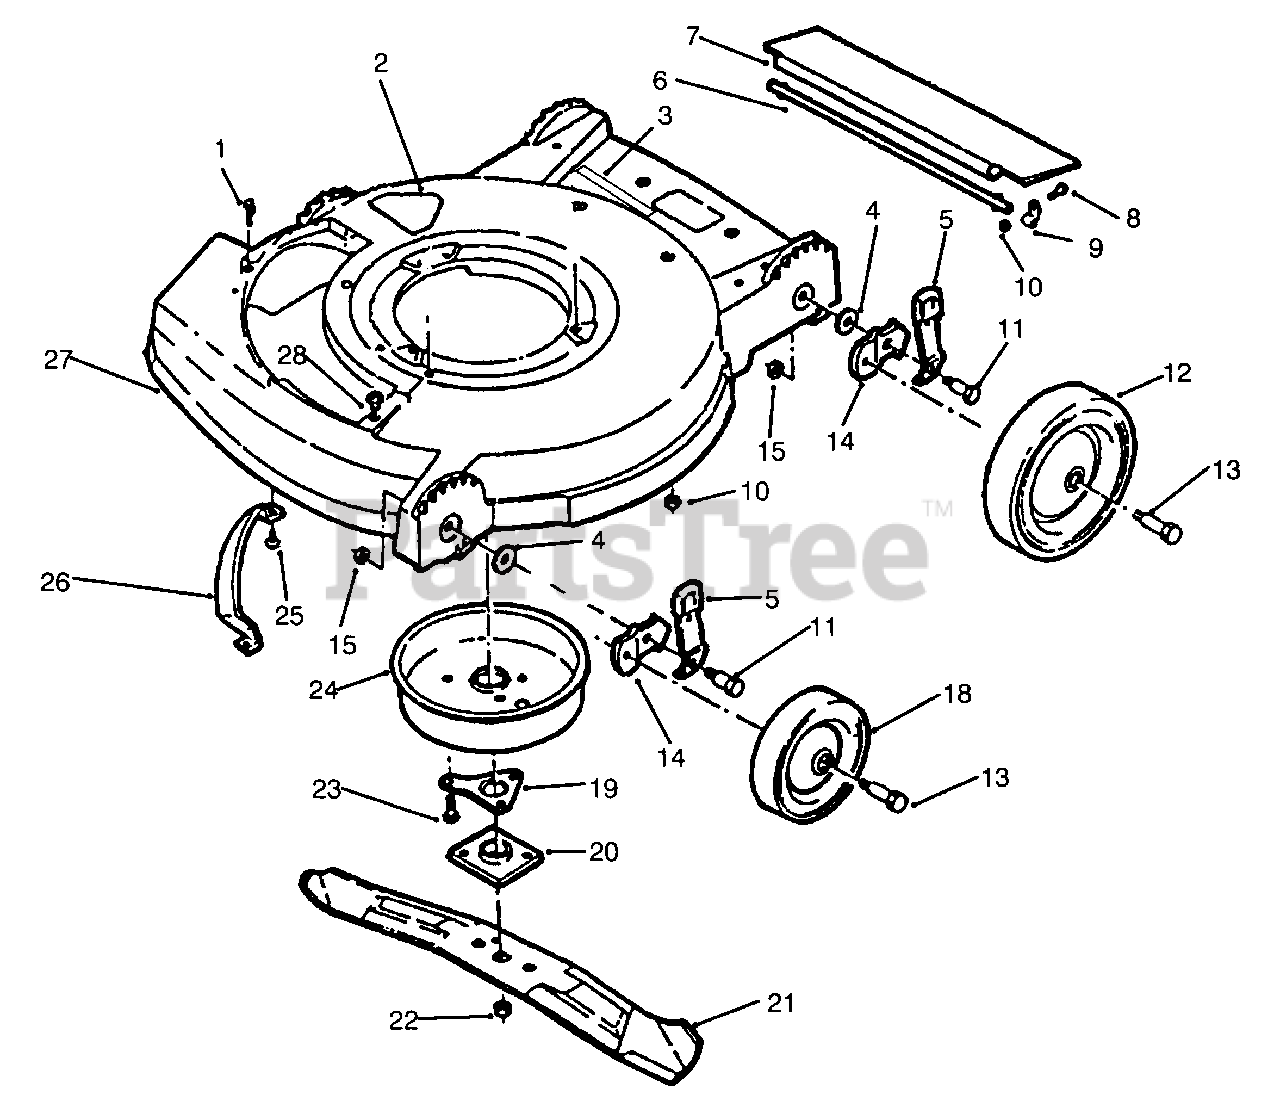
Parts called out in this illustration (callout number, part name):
1	Screw-SEMS, Plate Cover
2	Decal-Blade Warning
3	Decal-Warning
5	Knob & Spring-Adjustment
6	Rod-Shield, Trailing
7	Shield-Trailing
8	Screw
9	Clamp-Rod, Shield
10	Nut-Lock
11	Bolt-Shoulder
12	Wheel-Rear, 8"
13	Bolt-Wheel
14	Bracket-Wheel Adjustment
15	Nut-Lock
18	Wheel-Front, 6"
19	Plate-Support, Crankshaft
20	Collar & Plate
21	Blade-21"
22	Nut-Blade
23	Screw-Plate to Muffler Cov.
24	Cover-Muffler
25	Screw-Toe Bar to Housing
26	Toe Bar
27	Assembly-Housing(Incl. Ref. 2 & 28)
28	Grommet
